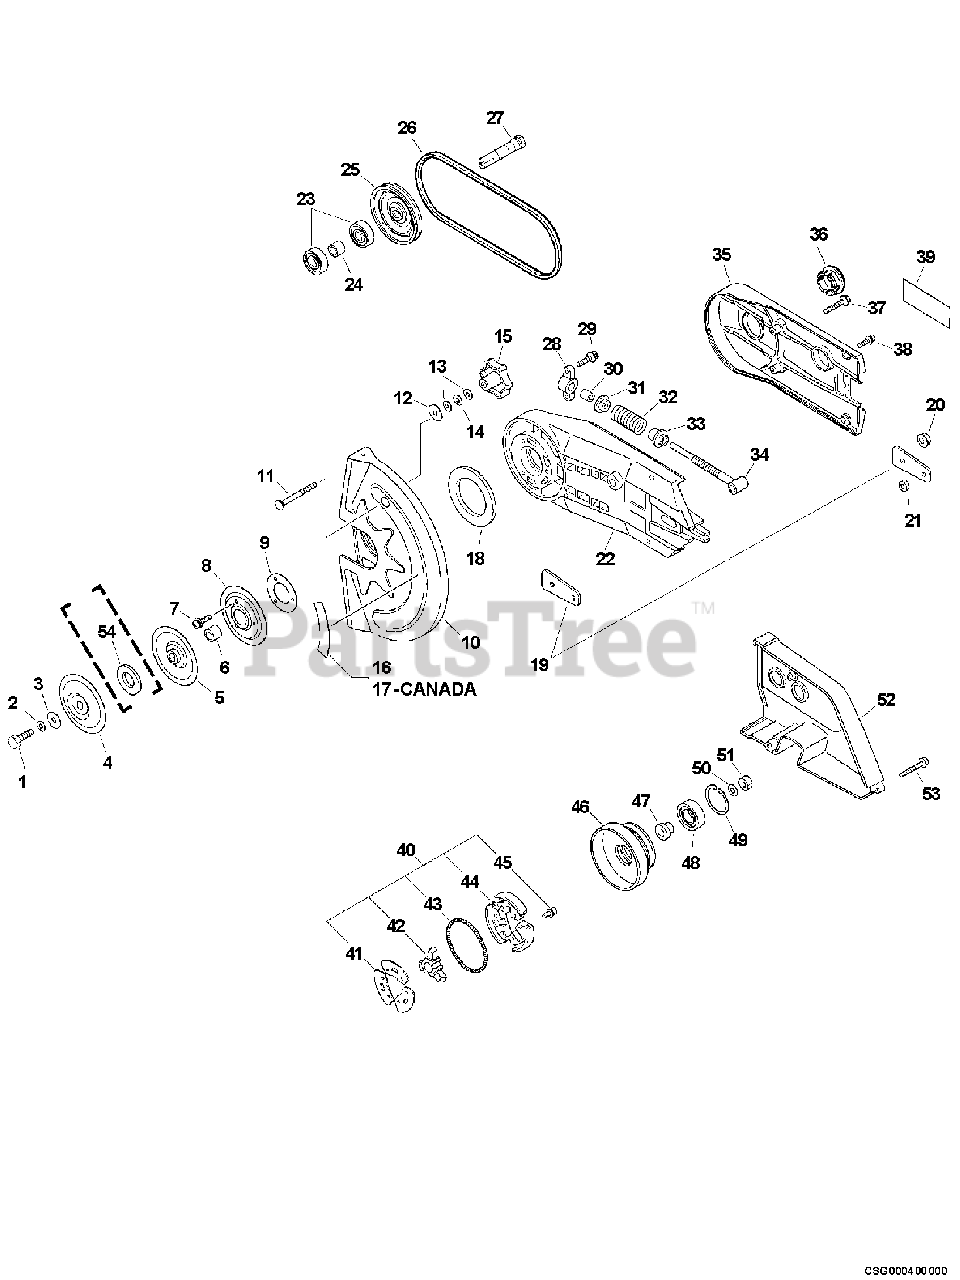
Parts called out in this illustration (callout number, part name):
2	WASHER, SPRING 10
4	FLANGE, CUTTER
5	FLANGE, CUTTER
7	SCREW 4×10
10	COVER, BLADE
13	WASHER 10.5×18×1.6
14	WASHER, SPRING 10
16	LABEL, CAUTION
19	SPACER, ARM
20	NUT, FLANGE M8×1.25
22	COVER, V-BELT
23	BEARING, BALL 6203
24	SPACER
28	SUPPORT
29	SCREW 5×20
30	SPACER, SHAFT
31	SPRING
32	SPRING, ADJUSTER
33	ADJUSTER
34	ROD, ADJUSTER
35	COVER, ARM - FRONT
37	SCREW 5×25
38	SCREW 5×20
39	LABEL - ECHO
40	CLUTCH ASSY
41	PLATE, CLUTCH
42	BOSS, CLUTCH
43	SPRING, CLUTCH
44	SHOE SET, CLUTCH (3PCS)
45	BOLT 4×6
46	DRUM, CLUTCH
48	BEARING, BALL 6201
49	RING, SNAP Ø32
50	WASHER, CLUTCH
51	NUT 8 LH
52	COVER, ARM
53	SCREW 5×25
54	WHEEL ADAPTER - 25 MM
